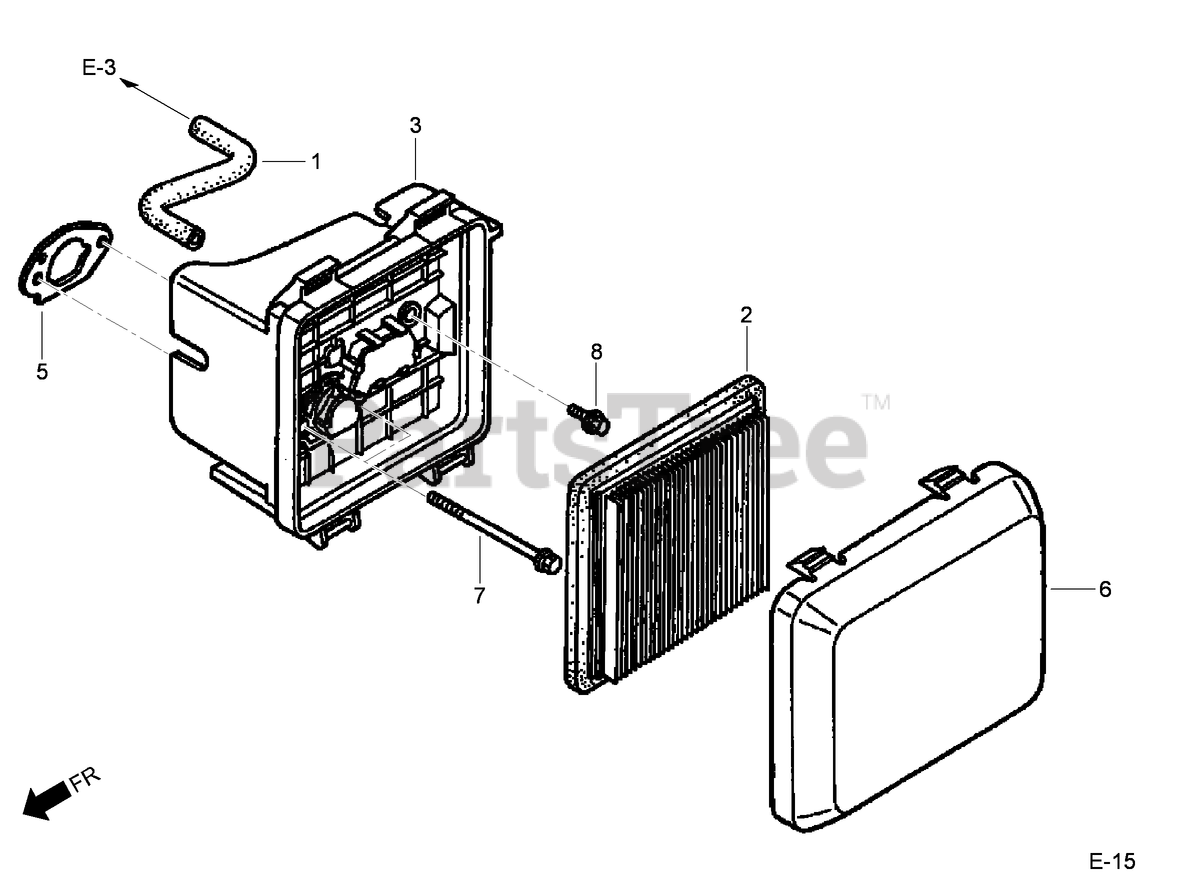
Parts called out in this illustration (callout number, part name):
1	TUBE-BREATHER
2	ELEMENT-CLEANER, AIR
3	AIR CLEANER CASE ASM
5	GASKET-CLEANER, AIR
6	COVER-CLEANER, AIR
7	BOLT-FLANGE (6X86) (C T200) (engine serial numbers up to 6349022)
7	BOLT, FLANGE (6X85) (C T200)
8	BOLT-FLANGE (6X14) (engine serial numbers up to 6624355)
